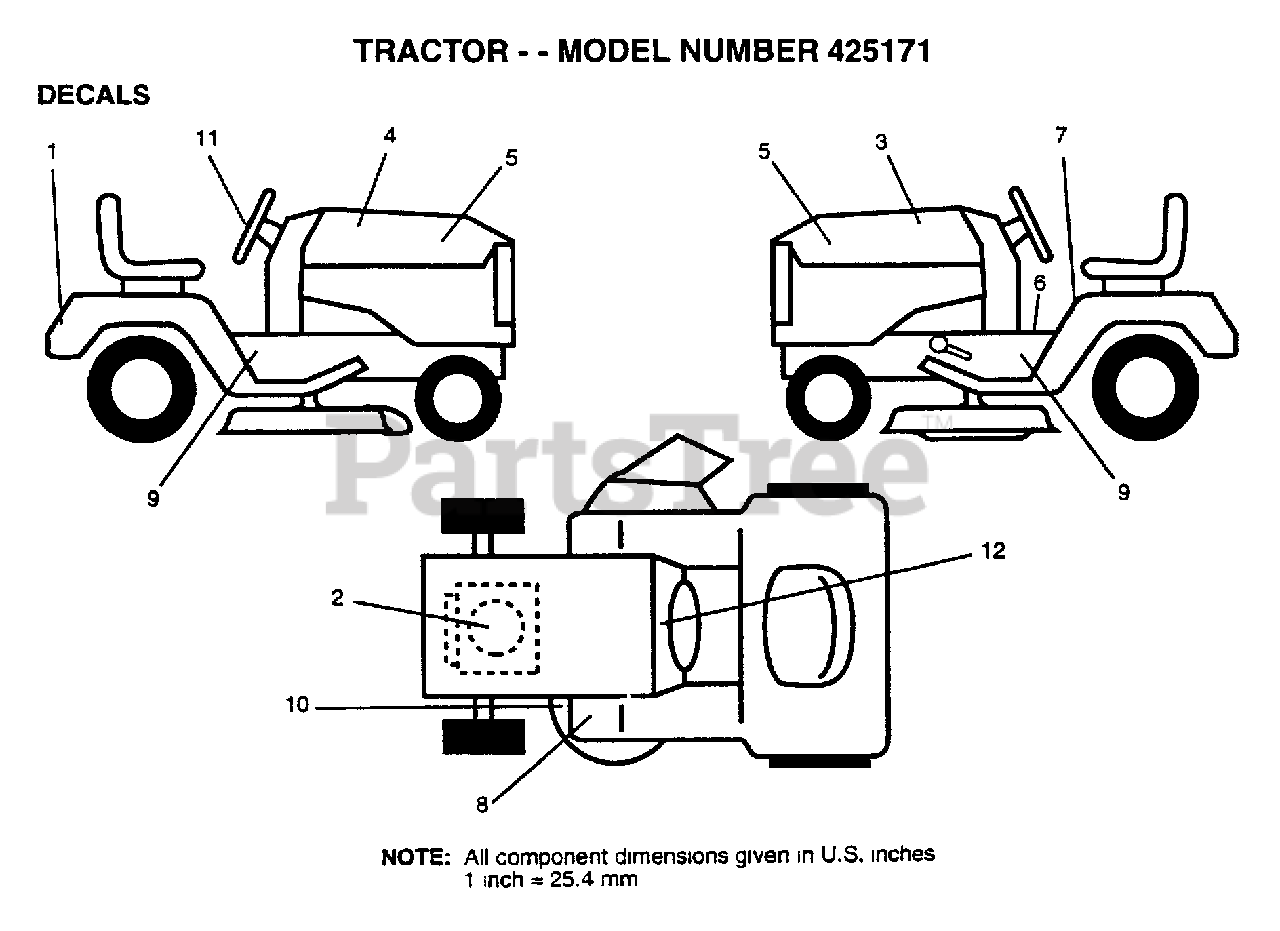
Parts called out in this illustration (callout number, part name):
1	DECAL.FENDER
2	DECAL.ENG.272559
3	DECAL.HD.LH.LOWER
4	DECAL.HD.RH.LOWES
6	DECAL BRAK PARK
7	DECAL
9	DECAL.CHASSIS
10	"DECAL.V.BELT.44"""
11	DECAL.WHL.STRG
12	DECAL.DASH.INST.
